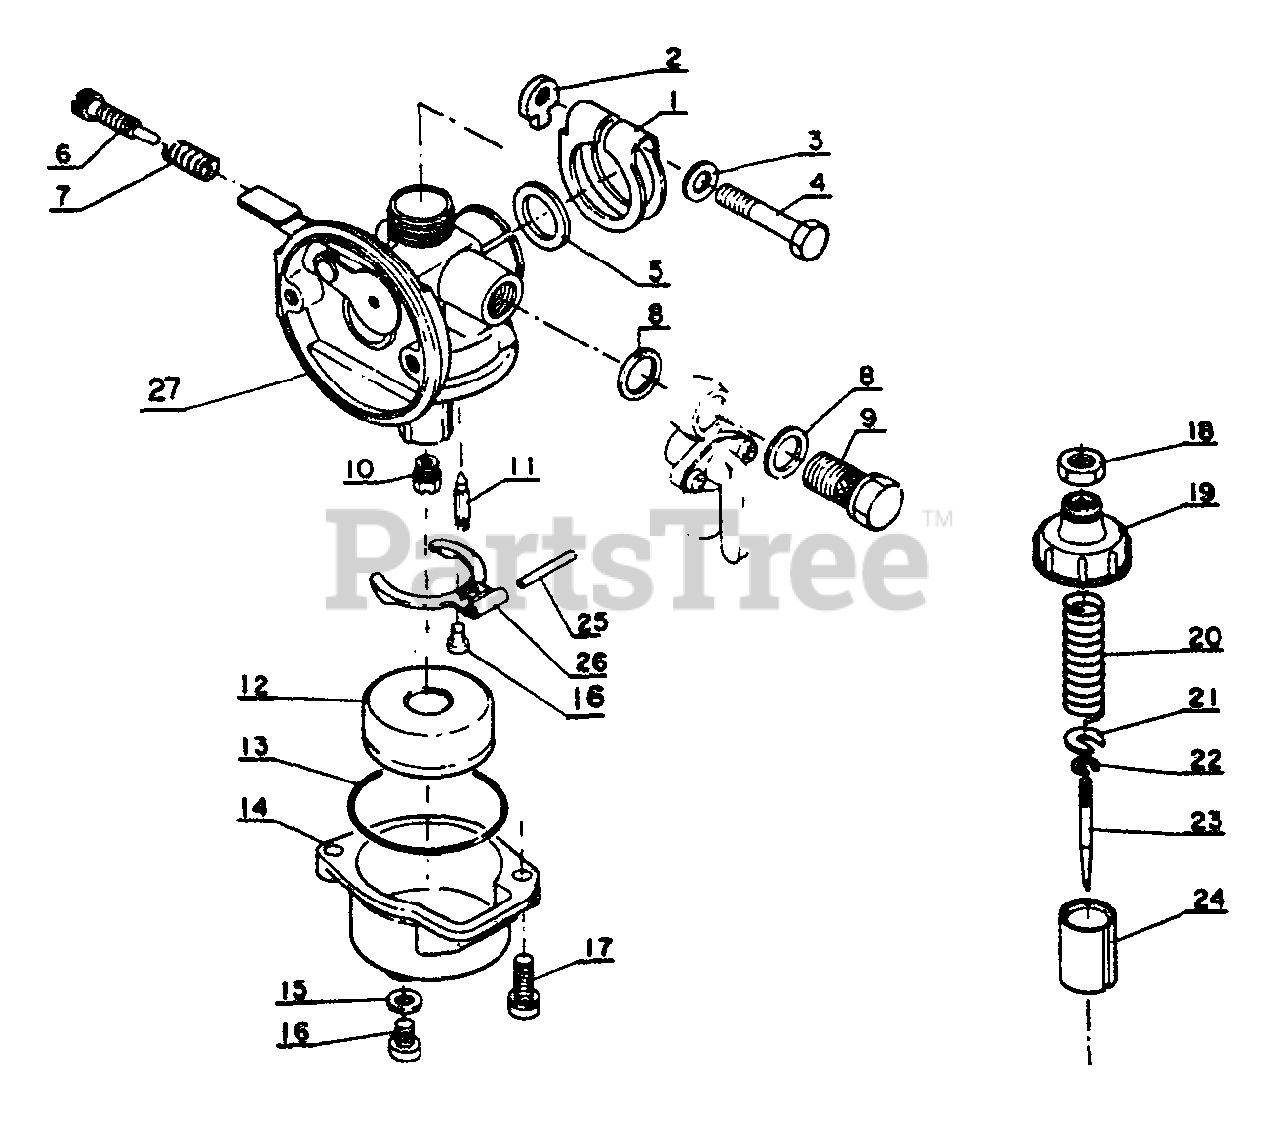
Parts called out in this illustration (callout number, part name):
1	CLIP
2	NUT
3	WASHER, FLAT 5.5×10×0.8
4	BOLT
6	SCREW, IDLE ADJUST
7	SPRING, IDLE ADJUST
9	BOLT, BANJO
10	VALVE, MIXTURE
11	VALVE, INLET NEEDLE
12	FLOAT
13	GASKET, CHAMBER
14	CHAMBER, FLOAT
16	SCREW 4×6
17	SCREW 4×12
18	NUT
19	COVER, TOP
20	SPRING, THROTTLE
21	SEAT, SPRING
22	E-RING
23	JET NEEDLE KIT
24	VALVE, THROTTLE
25	PIN
26	LEVER, METERING
27	BODY, CARBURETOR
